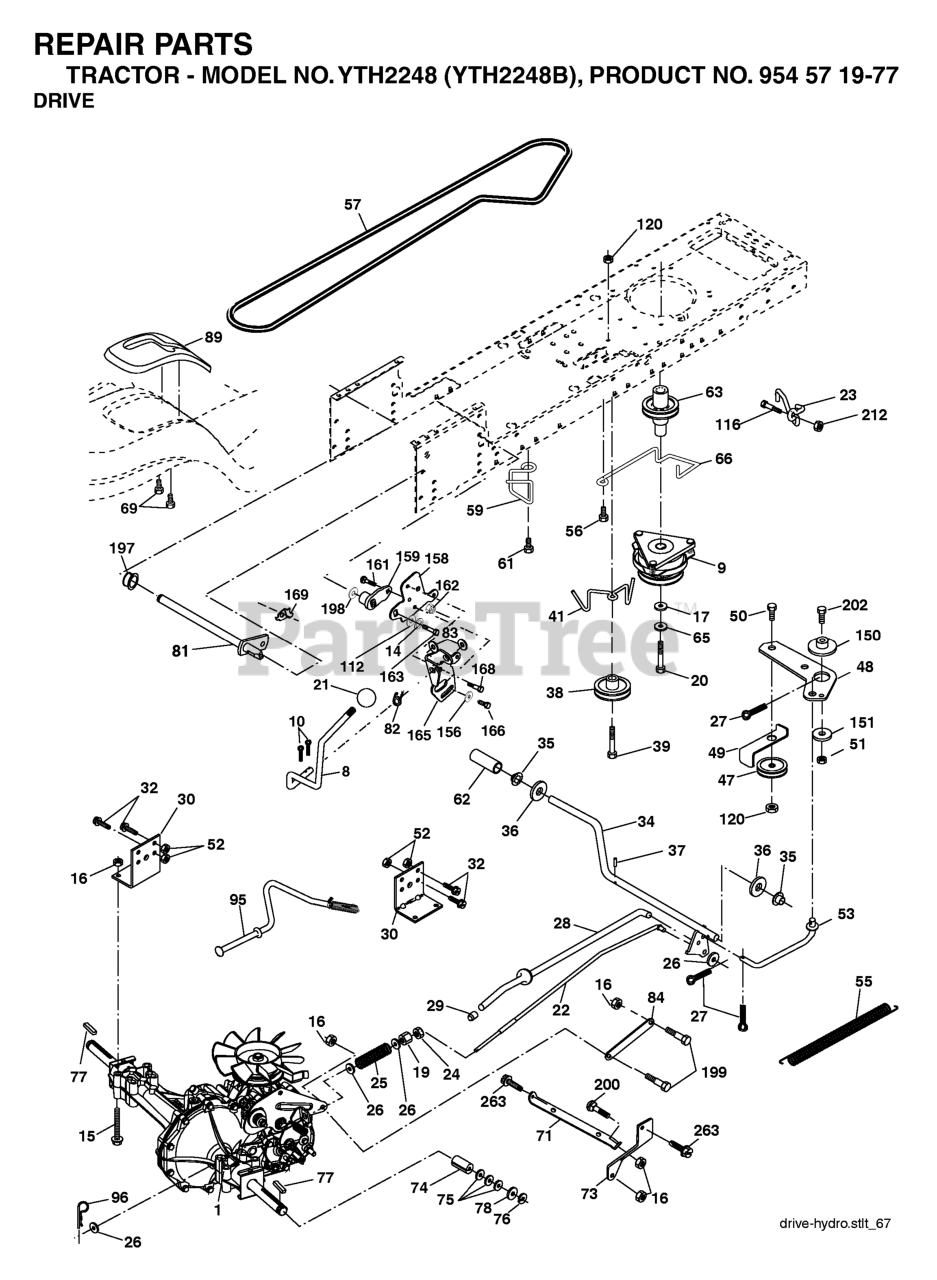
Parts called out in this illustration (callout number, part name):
8	ROD SHIFT FENDER ADJUST STLT
9	CLUTCH ELECTRIC
10	PIN COTTER
14	LOCKWASHER
15	BOLT HEX 5/16-18 GR 5
16	NUT.71038.31-18.HEX.NYLOCK
19	NUT
20	BOLT HEX 7/16-20X4-1/4"
21	KNOB.DELUXE.(PISTOL.GRIP).BLAC
22	ROD BRAKE HYDRO
23	BRKT ASM MTNG
24	NUT
25	SPRING ROD LT
26	WASHER
27	COTTER PIN
28	ROD, PARKING BRAKE
29	PLUNGER CAP
30	BRKT, TRNSXLE MNT 20"
32	BOLT
34	SHAFT, FOOT PEDAL
35	BEARING.NYLON
37	DRIVE PIN
38	PULLEY IDLER COMPOSITE
41	KEEPER, BELT IDLER
47	IDLER PULLEY
48	BELLCRANK, CLUTCH
49	RETAIN BELT
50	BOLT.3/8-16X1.50
52	LOCKNUT
53	LINK, CLUTCH LT
55	SPRING, RETURN LT
56	SCREW.3/8-16
57	DRIVE BELT, LTH & YTH TRACTORS
59	KEEPER, BELT CENTER
61	SCREW 3/8-16X.875
62	PEDAL COVER T
63	PULLEY- ENGINE
65	LOCKWASHER
66	KEEPER BELT ENGINE
69	SCREW.HI-LO.CONSOLE
71	STRAP TORQUE LH HYDRO
73	STRAP TORQUE RH HYDRO
74	SPACER AXLE
77	SQUARE KEY
81	SHAFT ASM CROSS TAPERED
82	SHIFT SPRING
83	WASHER
84	LINK TRANSAXLE
89	CONSOLE SHIFT STL AUTO
95	CONTROL ASM. BYPASS HYDRO
96	RETAINER M
116	BOLT D
120	NUT LOCK FLG 3/8-16 UNC
150	SPACER, RETAINER
151	WASHER 12/32X2X10GA
156	WASHER.SRRTD.5/16
158	BRACKET
159	RB HUB.SHIFT
161	BOLT
162	NUT.CROWNLOCK.1/4
165	RP BRACKET
166	CAPSCREW.HXHD.FLG.5/16-18X.625
168	BOLT.SHOULDER.5/16-18X
169	PLATE.FASTENING.CROSS.SHAFT
197	NYLINER SNAP 5/8" ID
198	WASHER.NYL.7/8IDX.105"HYD CR
199	BOLT SHOULDER 5/16-18 UNC
212	NUT
263	SCREW, 3/8-16X3/4
